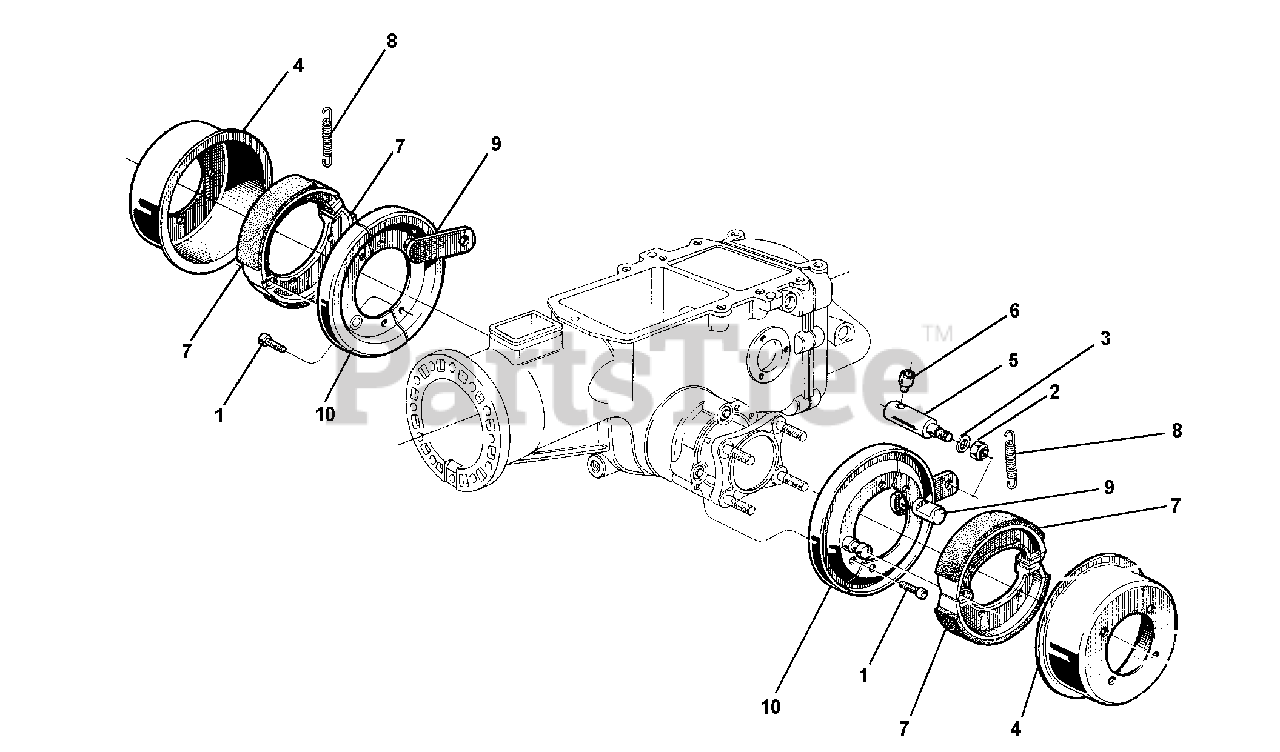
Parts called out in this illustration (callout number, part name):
1	SCREW TE CE M8 X 25
2	NUT, SELF LOCKING M8
3	WASHER, FLAT 8.4
5	SHEATH STOP
6	END, SHEATH
9	SEMIDISC LEVER
10	PIN HALF DISC
